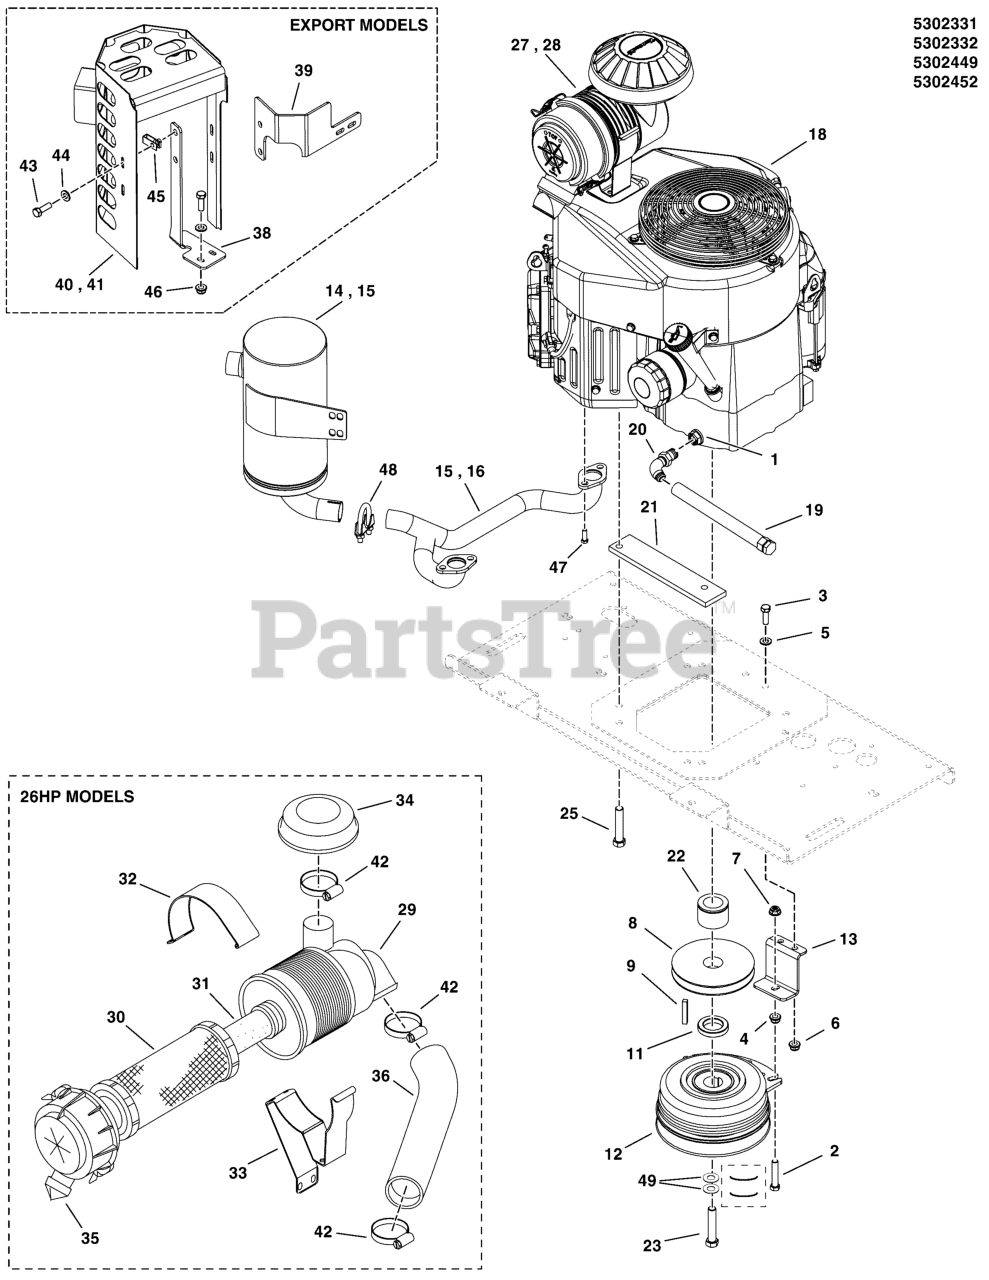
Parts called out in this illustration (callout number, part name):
1	ADAPTER-OIL DRAIN
2	BOLT, 5/16-18 X 1-1/2 GD5 YZ
3	BOLT, 5/16-18 X 1 GD5 YZ
4	NUT, 3/8-16 HEX JAM
5	WASHER, 5/16" SAE
6	NUT, 5/16-18 HEX NYLOCK FLANGE
7	NUT, 3/8-16 HEX NYLOCK FLANGE
8	PULLEY, CRANKSHAFT, 1.125 ID X 4.75 OD
9	KEY, 1/4 SQ X 5/8
11	SPACER, 1.13 X 1.75 X .32
12	* CLUTCH, 5218-134, WARNER
13	PLATE, CLUTCH ANCHOR
14	MUFFLER, OIL FILTER SIDE
15	MUFFLER, VERTICAL
16	MANIFOLD, VERTICAL
17	MANIFOLD, OIL FILTER SIDE
18	ENGINE, KAWASAKI
19	HOSE, OIL DRAIN
20	FITTING, 3/8NPT ELBOW, M-F
21	SPACER, ENGINE BLOCK, CCW - RED
22	SPACER, 1.13 X 1.75 X 1.625, CZ
25	BOLT,HEX FLG,SER GD5 3/8-16X2, PATCH,CZ
27	AIR FILTER
28	AIR FILTER ASSEMBLY
29	CASE, AIR FILTER
30	AIR FILTER, PRIMARY
31	AIR FILTER.SECONDARY
32	BRKT,AIR FILTER, KAV, OUTER
33	BRKT,AIR FILTER, KAV, INNER
34	RAIN CAP, AIR FILTER
35	DUST VALVE, AIR FILTR
36	AIR INLET TUBE, AIR FILTER
40	WELD, MUFFLER GUARD
41	WELD, MUFFLER GUARD
42	CLAMP, HOSE
43	BOLT, 1/4-20 X 1" GD5 CZ
44	WASHER, 1/4 SAE
45	BODY CLIP, 1/4-20 X 1/2 DEEP
46	NUT, 1/4-20 HEX NYLOCK FLANGE
47	SCREW
48	CLAMP, EXHAUST EXTENSION
49	BELLEVILLE WASHER 1.1875 X .442 X .089
